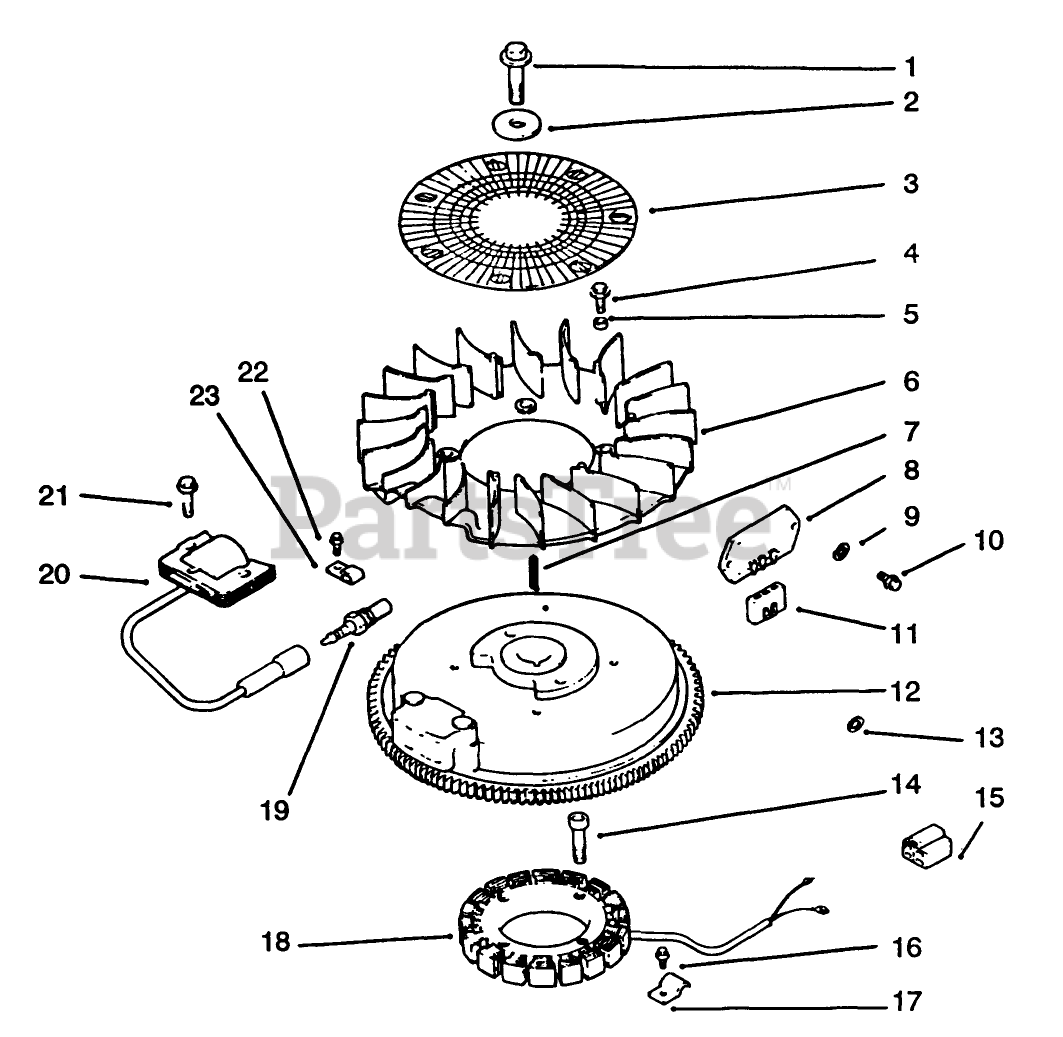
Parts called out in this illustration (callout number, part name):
1	Screw
3	Screen-Grass (Only On: 72042, 72063, 72062, 72043)
5	Spacer-Fan
6	Fan (Only On: 72042, 72063, 72062, 72043)
8	Rectifier-Regulator (Only On: 72042,72043,72062,72063)
9	Washer-Lock (Only On: 72042, 72063, 72062, 72043)
11	Connector
12	Flywheel ASM (Only On: 72042, 72063, 72062, 72043)
13	Washer-Flat (Only On: 72042, 72063, 72062, 72043)
15	Connector
17	Clip-Stator Harness (Only On: 72042, 72063, 72062, 72043)
18	Stator-15 amp
19	Spark Plug
20	Module-Ignition (Only On: 72042,72043,72062,72063)
